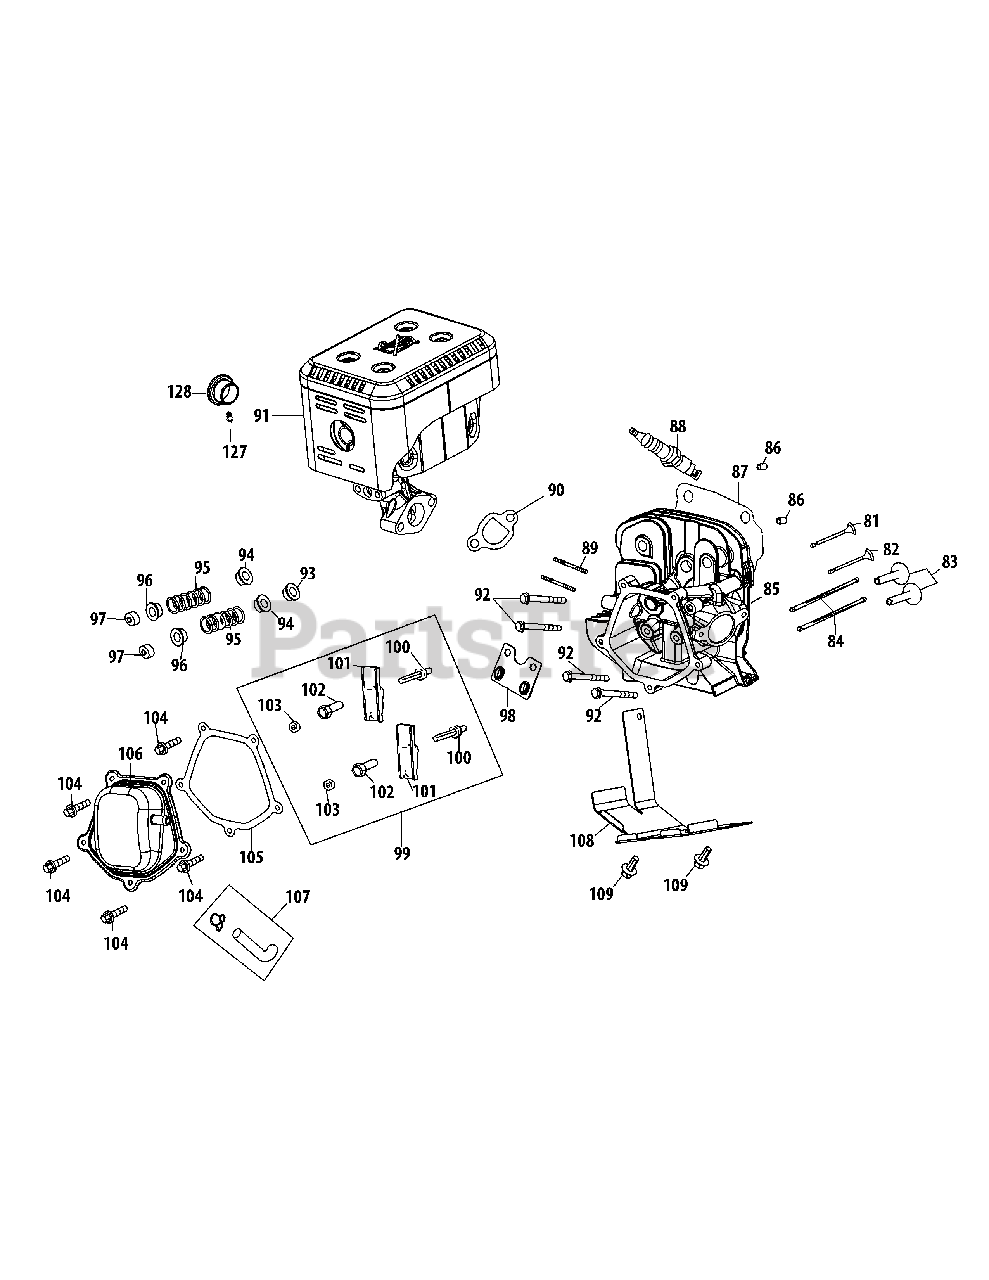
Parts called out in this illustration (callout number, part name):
81	Exhaust Valve
82	Intake Valve
83	Tappet
84	Push Rod Kit
85	Cylinder Head Assembly
86	Dowel Pin 12×20
87	Gasket,Cylinder Head
88	Spark Plug/F6Rtc
89	Muffler Stud M8×48.5
89	Muffler Stud Assembly
90	Muffler Gasket
91	Muffler Assembly
92	Bolt M10×1.25×80
93	Intake Valve Seal
94	Valve Spring Retainer
95	Valve Spring
96	Retainer,Ex.Valve Spring
97	Adjuster,Exh Valve
98	Push Rod Guide
99	Rocker Arm Assembly
100	Bolt,Pivot
101	Rocker Arm
102	Adjusting Nut ,Valve
103	Nut,Pivot Locking
104	Valve Cover Bolt
105	Valve Cover Gasket
106	Valve Cover
107	Breather Hose Assembly
108	Air Shield
109	Bolt M6×12
127	Bolt, Self Tapping
128	Spark Arrestor
